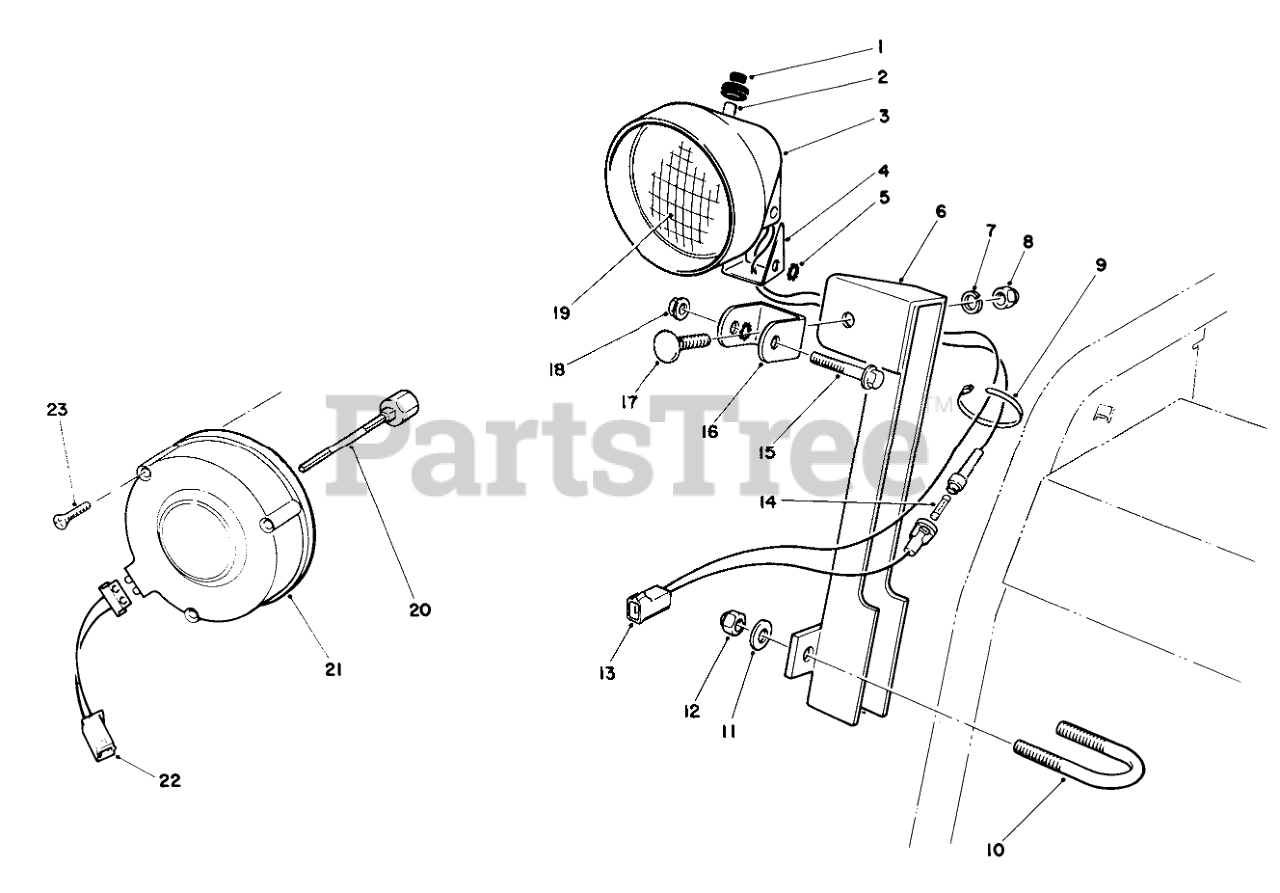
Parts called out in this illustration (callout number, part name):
1	BOOT-SWITCH
2	SWITCH ASM
3	Bucket-Headlamp
4	TO BE DISCONTINED-NOT NEEDED ON PRODUCT
5	WASHER-LOCK
6	Mount-Lamp
7	WASHER-LOCK
8	NUT-HEX
9	TIE-CABLE
10	U-BOLT
11	WASHER-PLAIN
12	NUT-LOCK, NI
13	WIRE ASM
14	Fuse-7-1/2 Amp.
15	SCREW-HH
16	BRACKET
17	BOLT-CARR
18	NUT-HF
19	BEAM-SEALED
20	Shaft-Alternator, 3 Inch
21	Alternator
22	Connector-Wire
23	SELF TAP SCREW
